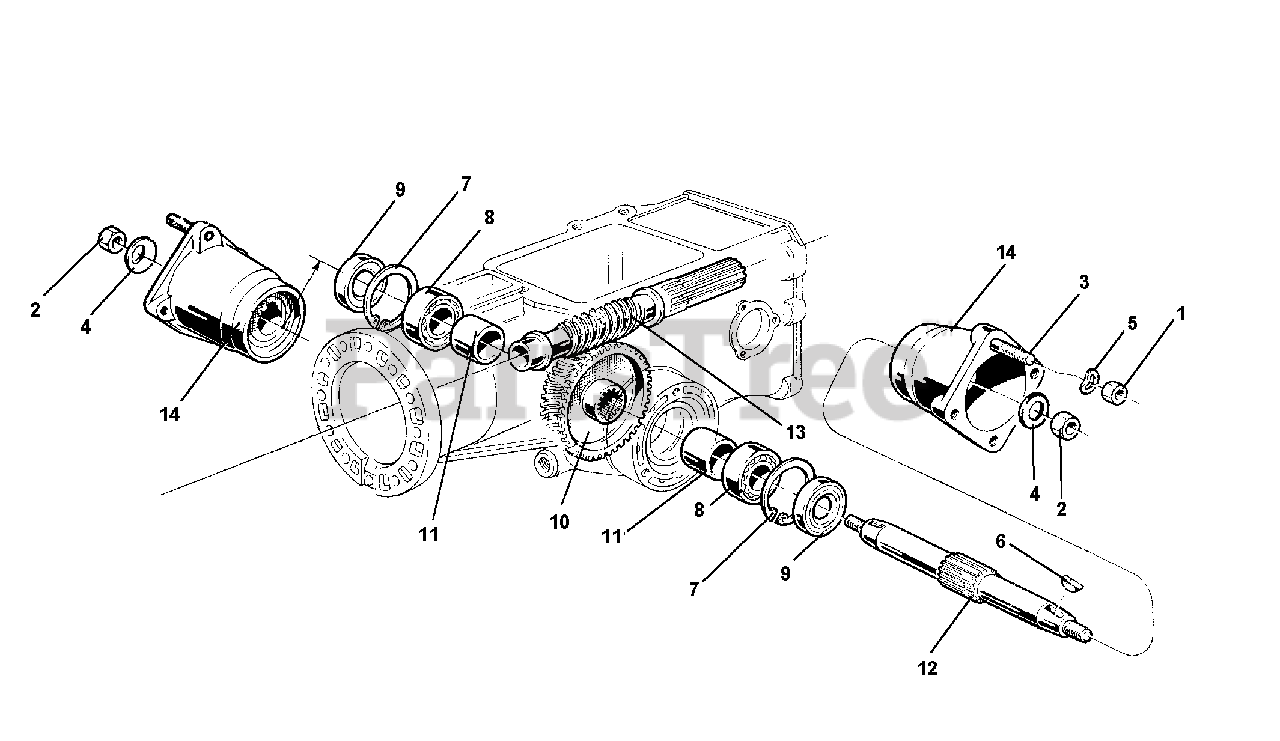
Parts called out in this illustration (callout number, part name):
2	NUT, SELF LOCKING M12
3	STUD M10 X 40 X 22 X 14
4	SUPER WASHER 12 DIN 6796
5	WASHER, LOCK 10.5
6	KEY 6 X 10 UNI 6606
7	CIRCLIP, INTERN D 52
8	BEARING 25 X 52 X 15 6205
9	SEAL, OIL 25 X 52 X 10 STANDARD
10	GEAR Z 49, LH MOTOR MOWER
12	WHEEL SHAFT
14	HUB, WHEEL, WITH STUDS
